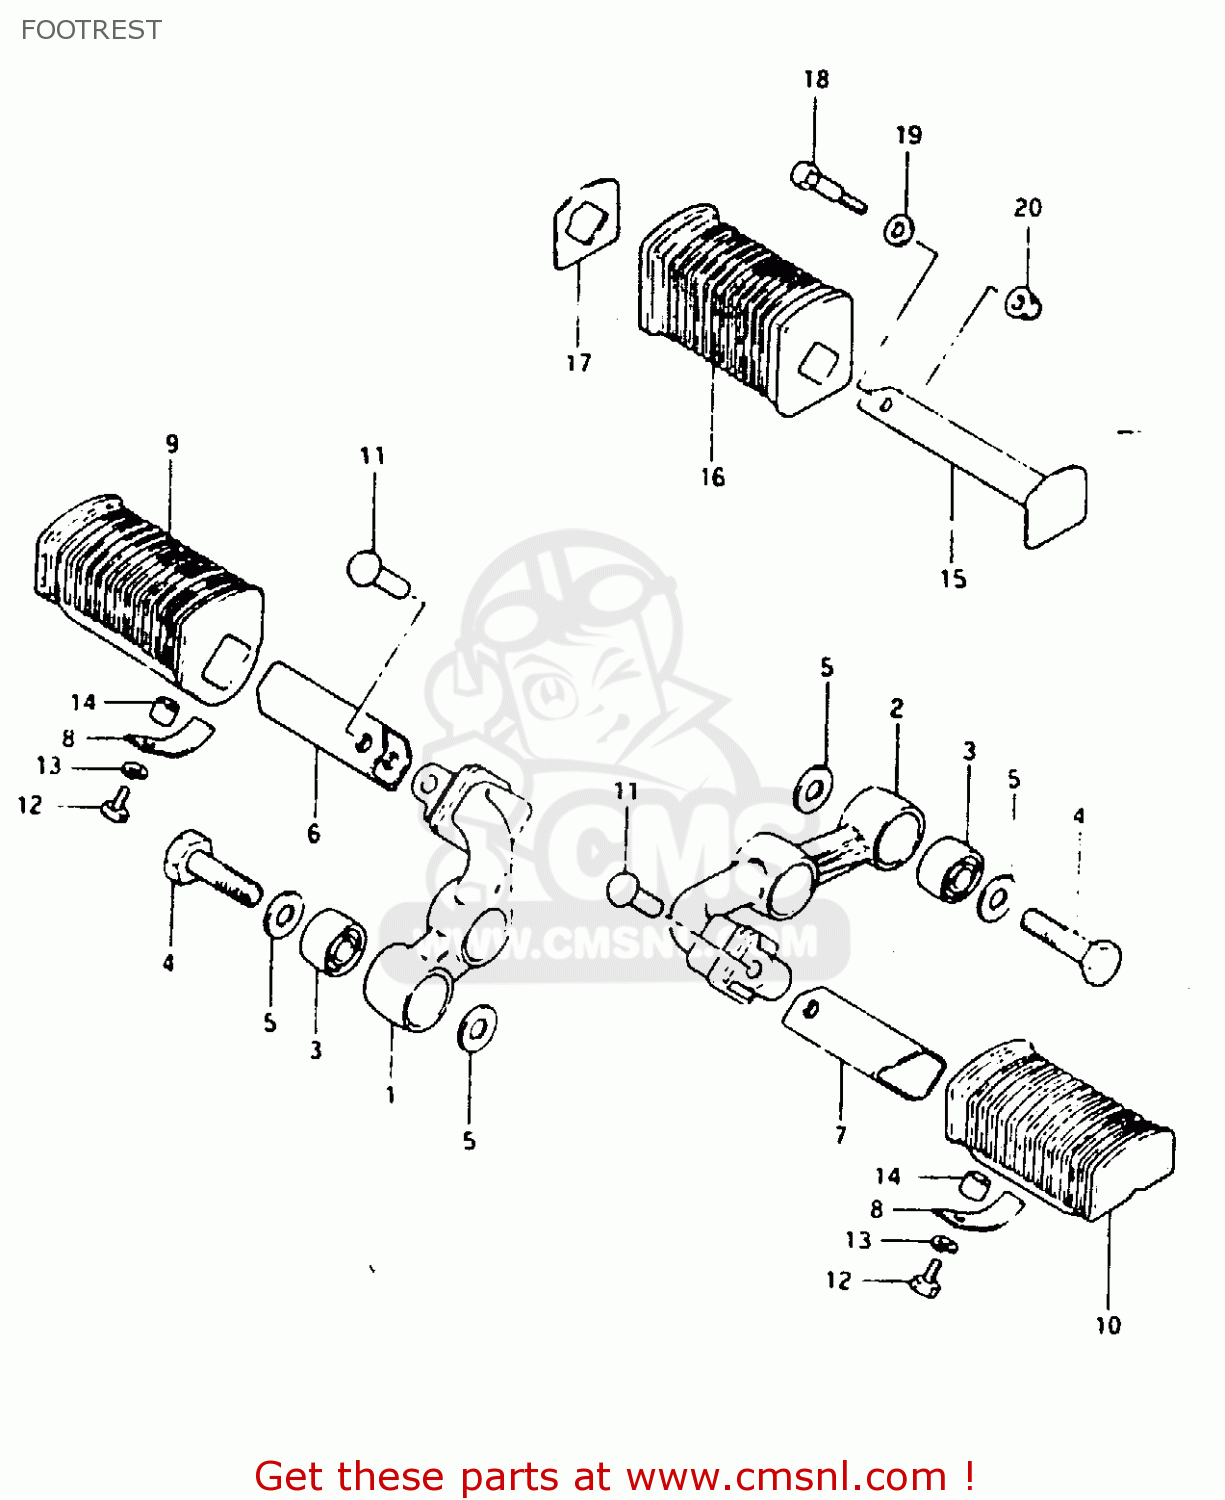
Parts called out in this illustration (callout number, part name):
1	BAR, FOOTREST RH
2	BAR, FOOTREST LH
3	BUSH
4	BOLT
5	WASHER
6	HOLDER, COVER RH
7	HOLDER, COVER LH
8	PLATE, FOOTREST STOPPER
9	RUBBER,FR FOOTREST,R
10	RUBBER,FR FOOTREST,L
11	RIVET
12	BOLT, UPPER
13	LOCK WASHER
14	SPACER(6.5X10.5X6.5)
15	BAR, RH
16	RUBBER,PILLION FOOTREST
17	WASHER,PILLION FOOTREST RUBBER
18	BOLT(6X40)
19	WASHER
20	NUT
